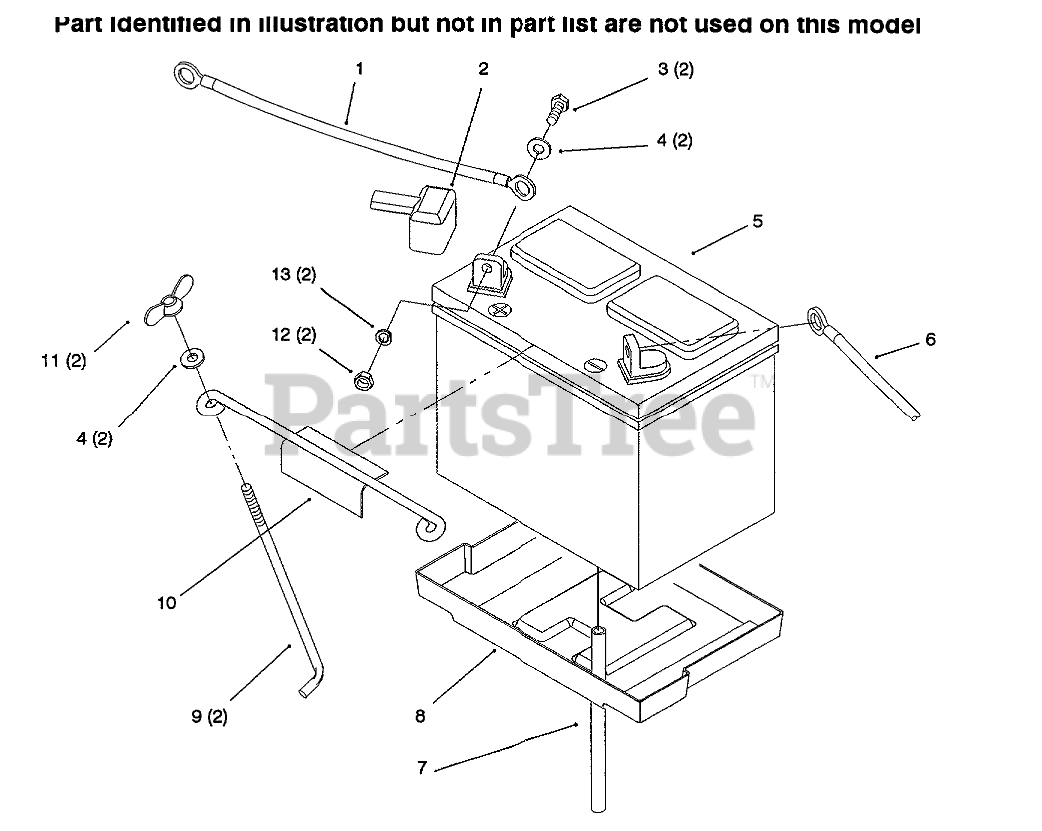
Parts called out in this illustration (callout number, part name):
1	ASS'Y-WIRE
2	Boot
3	SCREW-HH
4	WASHER-FLAT
5	Battery
6	ASS'Y-WIRE
7	TUBE-21" BATTERY DRAIN
8	TRAY-BATTERY
9	HOOK-BATTERY RETAIN
10	HOLDDOWN-BATTERY
11	NUT-WING
12	NUT-LOCK, NI
13	WASHER-LOCK
